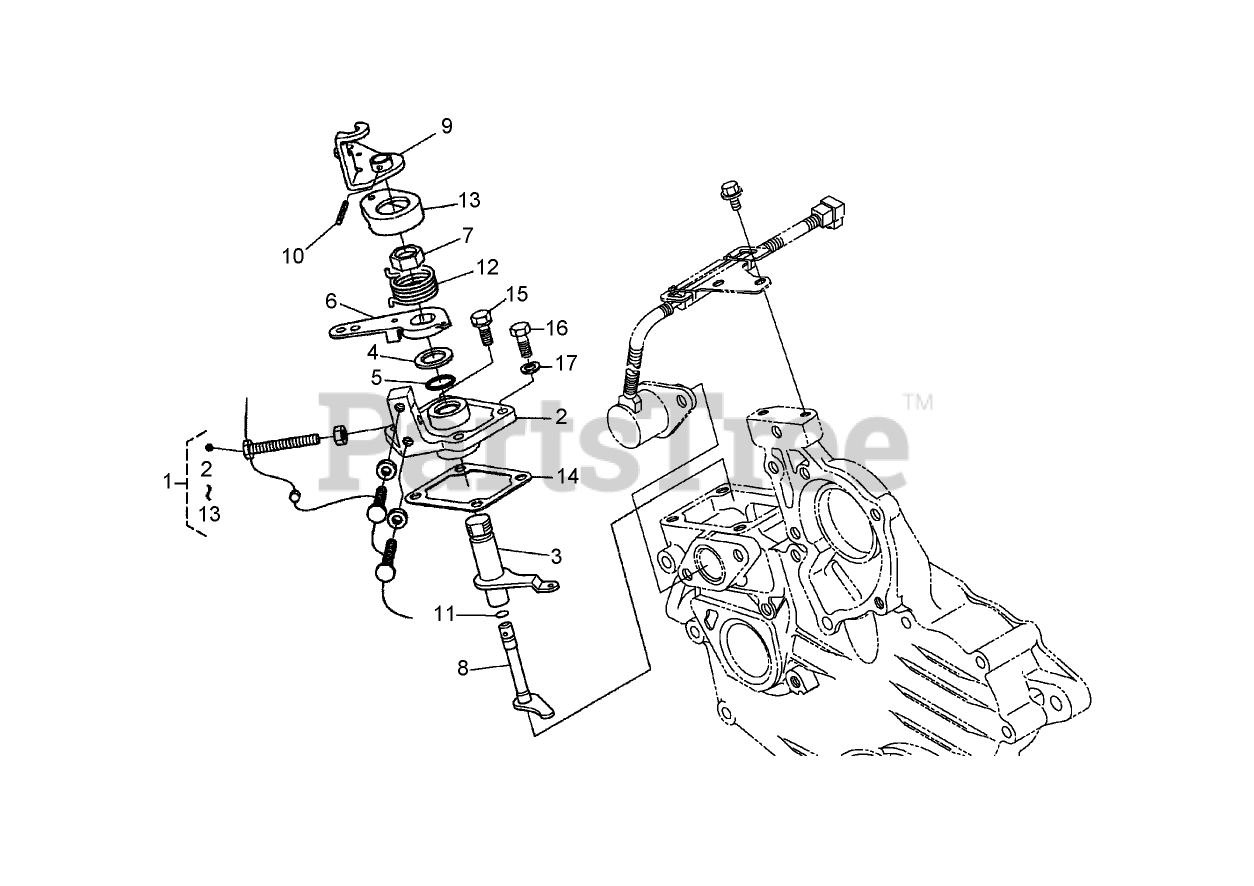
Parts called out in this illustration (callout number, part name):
1	SPEED CONTROL PLATE ASM
2	PLATE-CONTROL, SPEED
3	LEVER-GOVERNOR
4	COLLAR
5	O-RING
6	LEVER-CONTROL, SPEED
7	NUT-CONTROL, SPEED
8	SHAFT-LEVER
9	LEVER-STOP, ENGINE
10	PIN-SPRING
11	O-RING
12	SPRING-RETURN
14	GASKET-PLATE, CONTROL
17	GASKET
